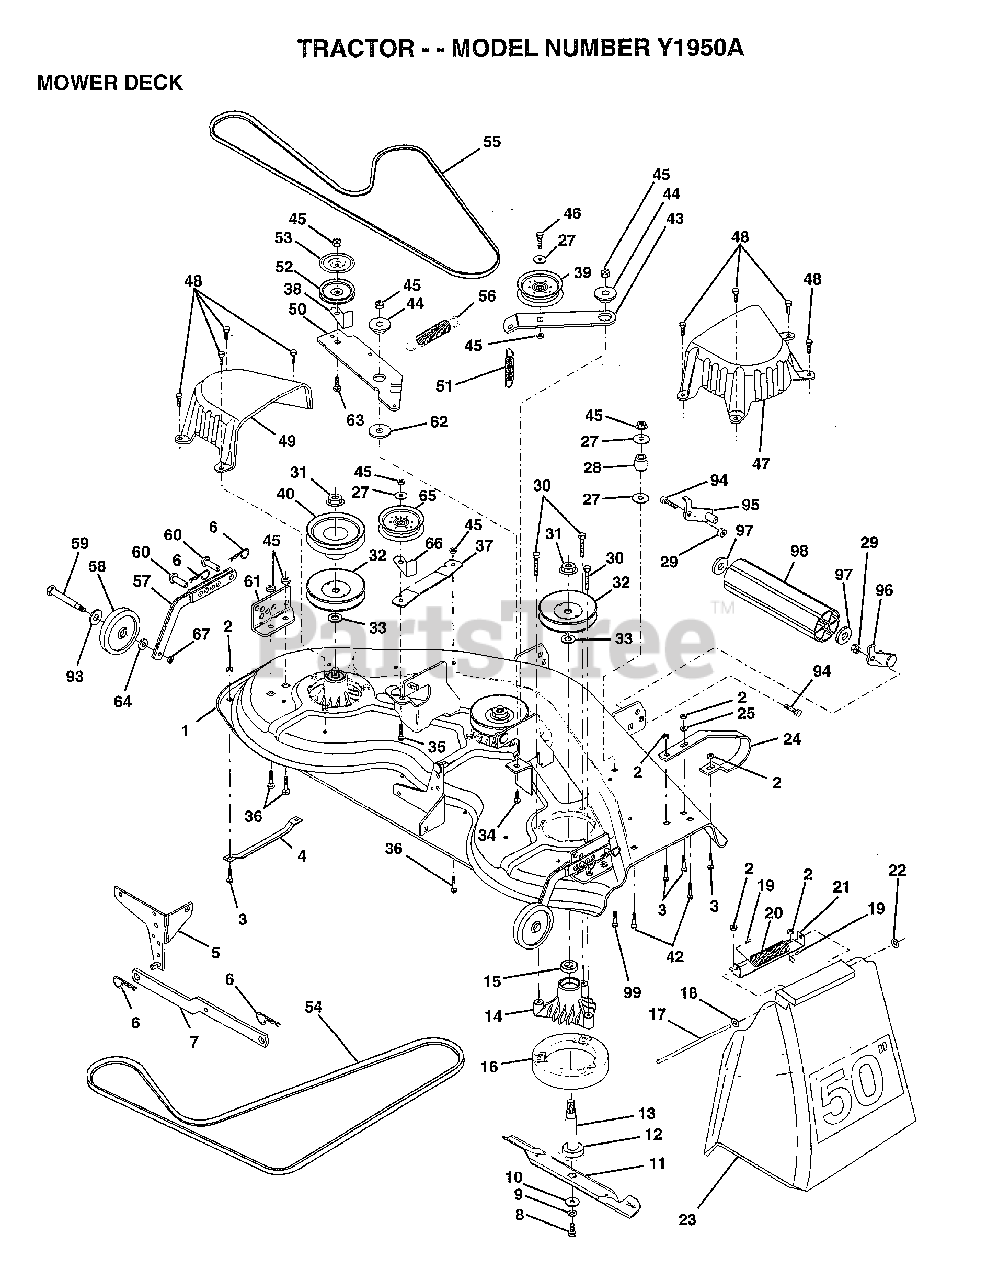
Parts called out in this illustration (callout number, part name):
1	DECK ASM MWR 50VT
4	RUNNER-LH M
5	BRKT.ASM.SW.44/50
8	BLADE BOLT
10	WASHER.HARD.BLADE
11	"BLADE.50"" HD"
12	BEARING.BALL
13	SHAFT.ASM.W/BRNG
14	HOUSING.MAND.44.V
15	BEARING
16	STRIPPER RND MWR
17	ROD-HINGE T
18	WASHER
19	CAP-SLEEVE LT
20	SPRING TORSION
21	BRKT DEFLECTOR
22	NUT PUSH M
23	DEFLECTOR
24	"RUNNER RH 50"" DK"
25	WASHER M
27	WASHER
29	NUT
33	WASHER
34	BOLT.3/8-14X1.25
35	BOLT
36	BOLT D
37	STIFFENER.ARM.IDL
39	FLAT IDLER PULLEY
40	"PULLEY.DRIVEN.44"""
42	BOLT
43	"ARM.IDLER.SEC.44"""
44	SPACER RETAINER
47	"COVER.MAND.RH.44"""
48	SCREW.1/4-20X5/8
49	COVER.MANDREL.LH
50	ARM.IDLER.PRIMARY
51	"SPRING.SEC.44""VEN"
52	PULLEY.IDLER.VGRO
53	SHIELD.IDLER.44.V
54	BELT V PRIM 50
55	BELT-V.SEC.46.KEL
56	SPRING.EXT.DECK.
57	BAR.ASM.GUAGE.WHL
58	WHEEL.GAGE.BLK.PL
59	BOLT M
60	PIN.CLEVIS
61	BRACKET.GUAGE.WHL
62	HARDENED WASHER
63	BOLT.3/8-16X1.50
64	WASHER
65	IDLER-FLAT T
67	LOCKNUT
93	WASHER
94	BOLT
97	WASHER
99	BOLT
